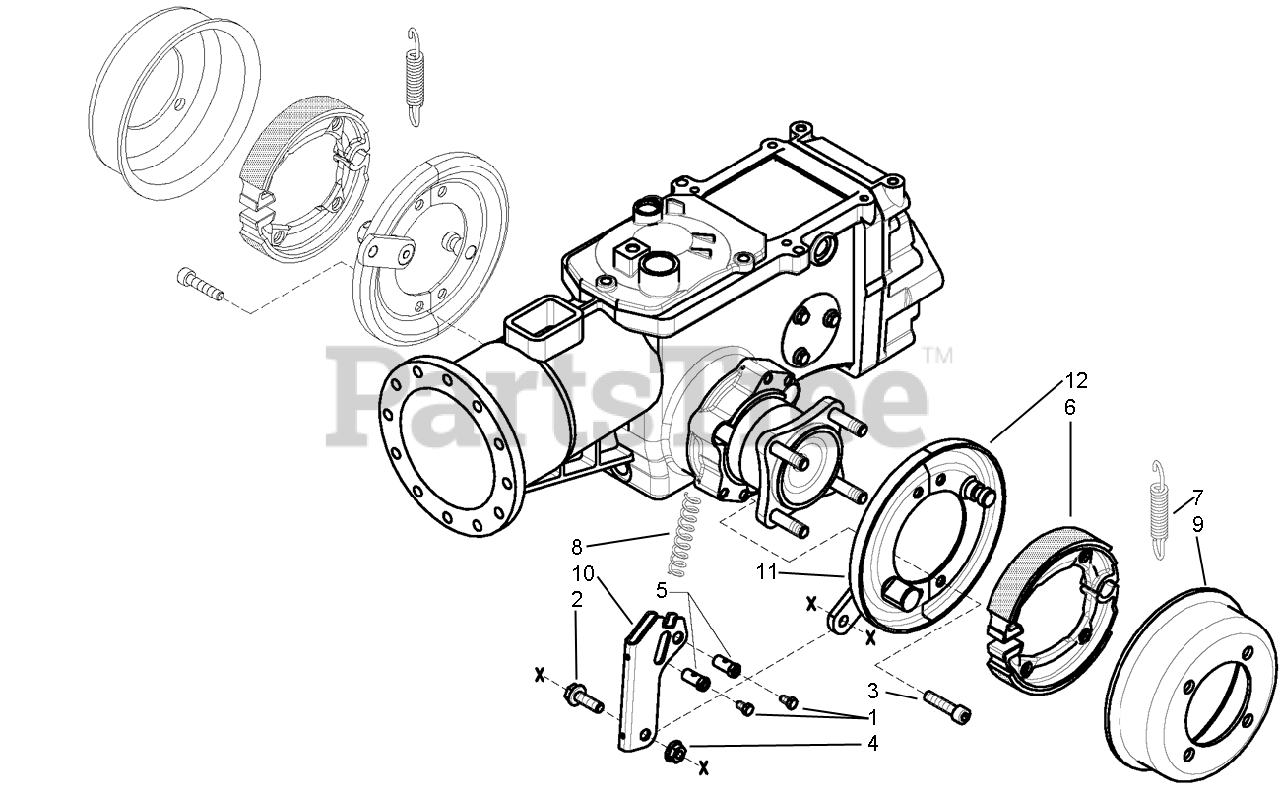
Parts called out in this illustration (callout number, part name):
1	SCREW M6X16
2	SCREW M8X25
3	SCREW, M8X25
4	NUT, LOCK M8 FLANGED
5	SCREW, CLAMPING
11	LEVER, HALF DISK COMPLETE
12	PIN, HALF DISC COMPLETE
